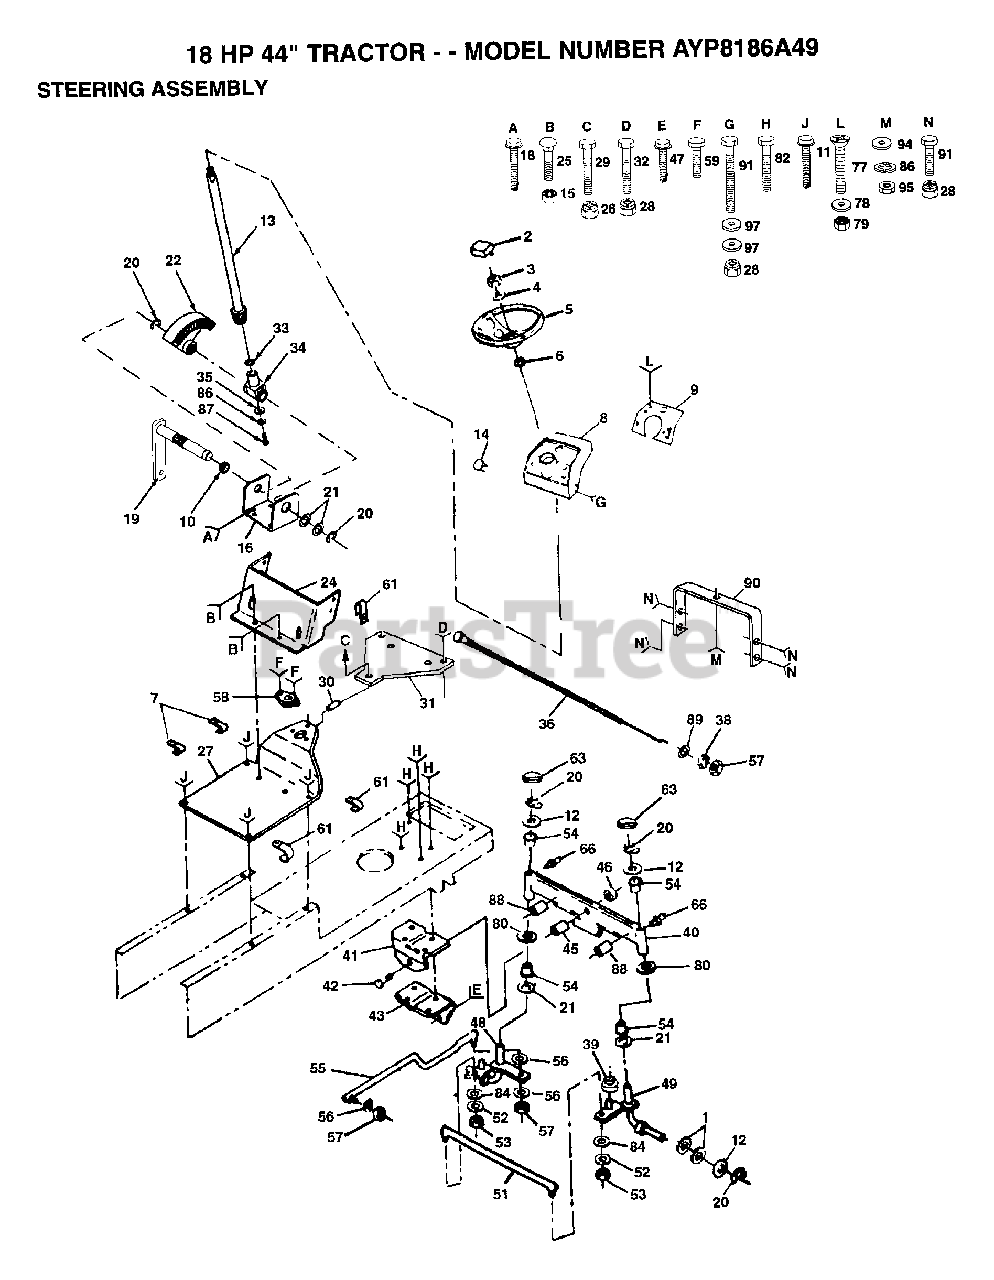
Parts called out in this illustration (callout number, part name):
1	WASHER
2	ST WHL INSERT CAP
4	WASHER
6	ADAPTER LT
7	"CLIP,INSULATOR"
8	DASHBOARD BLACK
9	PLATE DASH SILKSC
10	NYLINER T
11	SCREW LT
12	WASHER
13	STEERING SHAFT
14	PLUG-DASH T
16	"BRKT,STEERING"
18	SCREW
20	RING
21	WASHER .T
22	GEAR SECTOR
24	DASH ASSY LT
25	SCREW
26	NUT
29	BOLT
30	SPACER
31	PLATE.SUPT.BATTER
33	THRUST WASHER
34	SUPPORT.SHAFT
36	CHOKE CONTROL
38	LOCKWASHER
39	BUSHING SPIN STOP
41	SUPPORT-SADDL T
42	BOLT LT
43	SUPPORT.SADDLE.FT
45	BEARING
46	"NUT-LOC,FLANGE LT"
47	SCREW LT
48	SPINDLE LH
49	SPINDLE RH
51	TIE ROD
52	LOCKWASHER
53	NUT.LOCK.5/16-24
54	COL. SRTG. BEAR.
56	LOCKWASHER
61	CLIP T
63	CAP
66	ZERK M
77	SCREW
78	WASHER
80	WASHER
82	SCREW SPECIAL
84	WASHER M
86	LOCKWASHER
87	"SCREW,SPECIAL"
88	AXLE PIN
89	WASHER
90	SUPPORT ASS'Y
94	WASHER PM
97	WASHER
